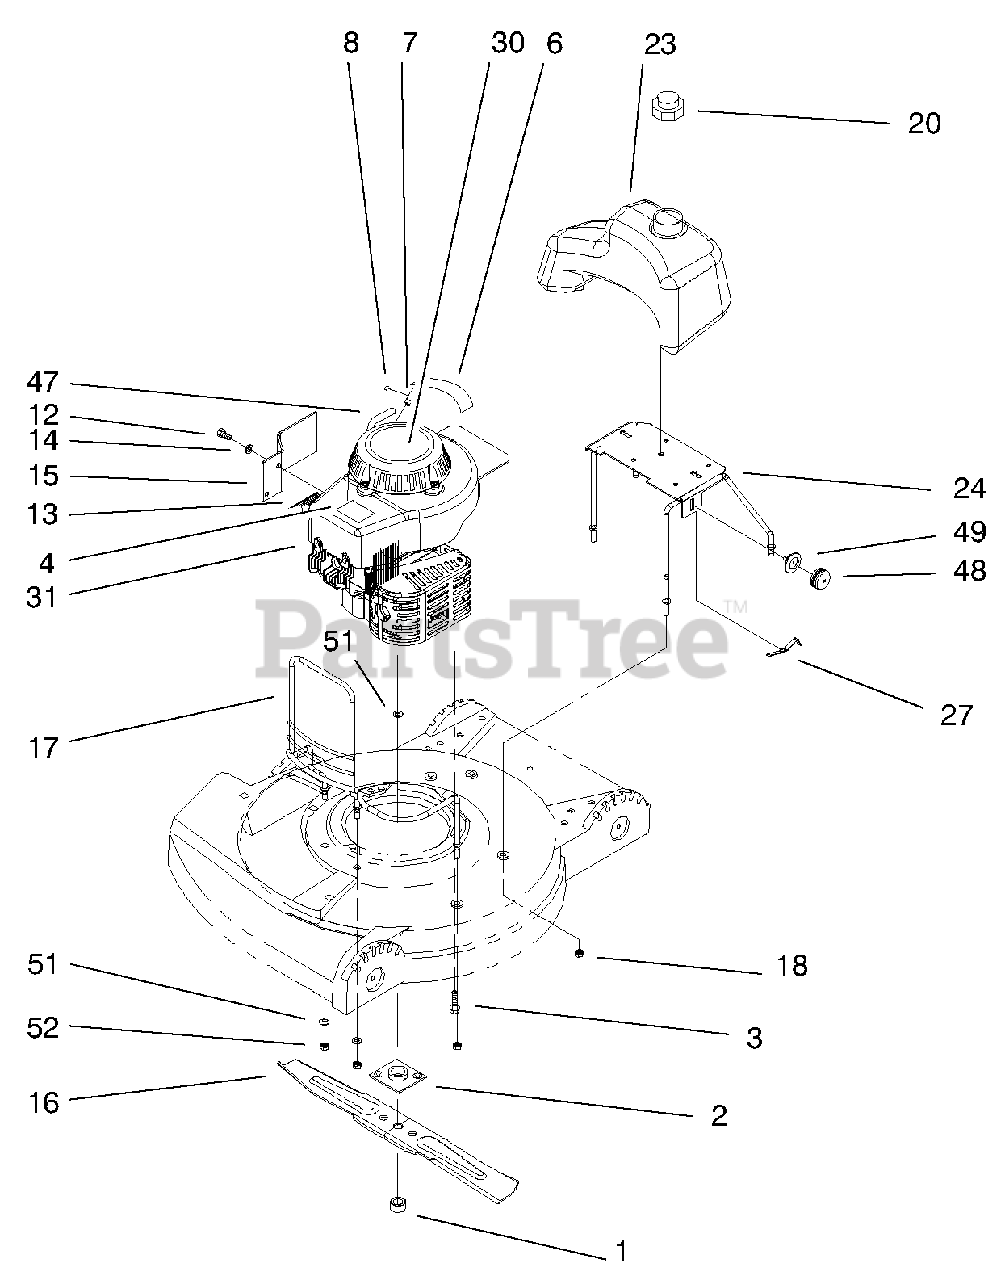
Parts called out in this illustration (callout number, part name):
1	Nut-Blade
2	ASM-Plate & Collar
3	Screw-Sems
4	Decal-Lawn Boy
6	Decal-Fuel Mix
7	Rope Stop
10	Screw-HWH
12	Screw-HH
13	Spring-Compression
14	Washer-Lock
15	Guard-Brake
16	Blade-21" Whirl
17	Guard-Engine
18	Locknut
20	ASM-Fuel/Oil Cap
21	Screw-Throttle Cable
22	Nut-Throttle Cable
23	Tank-Fuel
24	Tank Bkt ASM
30	Decal-Recoil
31	Engine-Commercial Int'l
47	Gas Line
48	Bulb-Primer
49	Body-Primer
51	Washer-Flat
